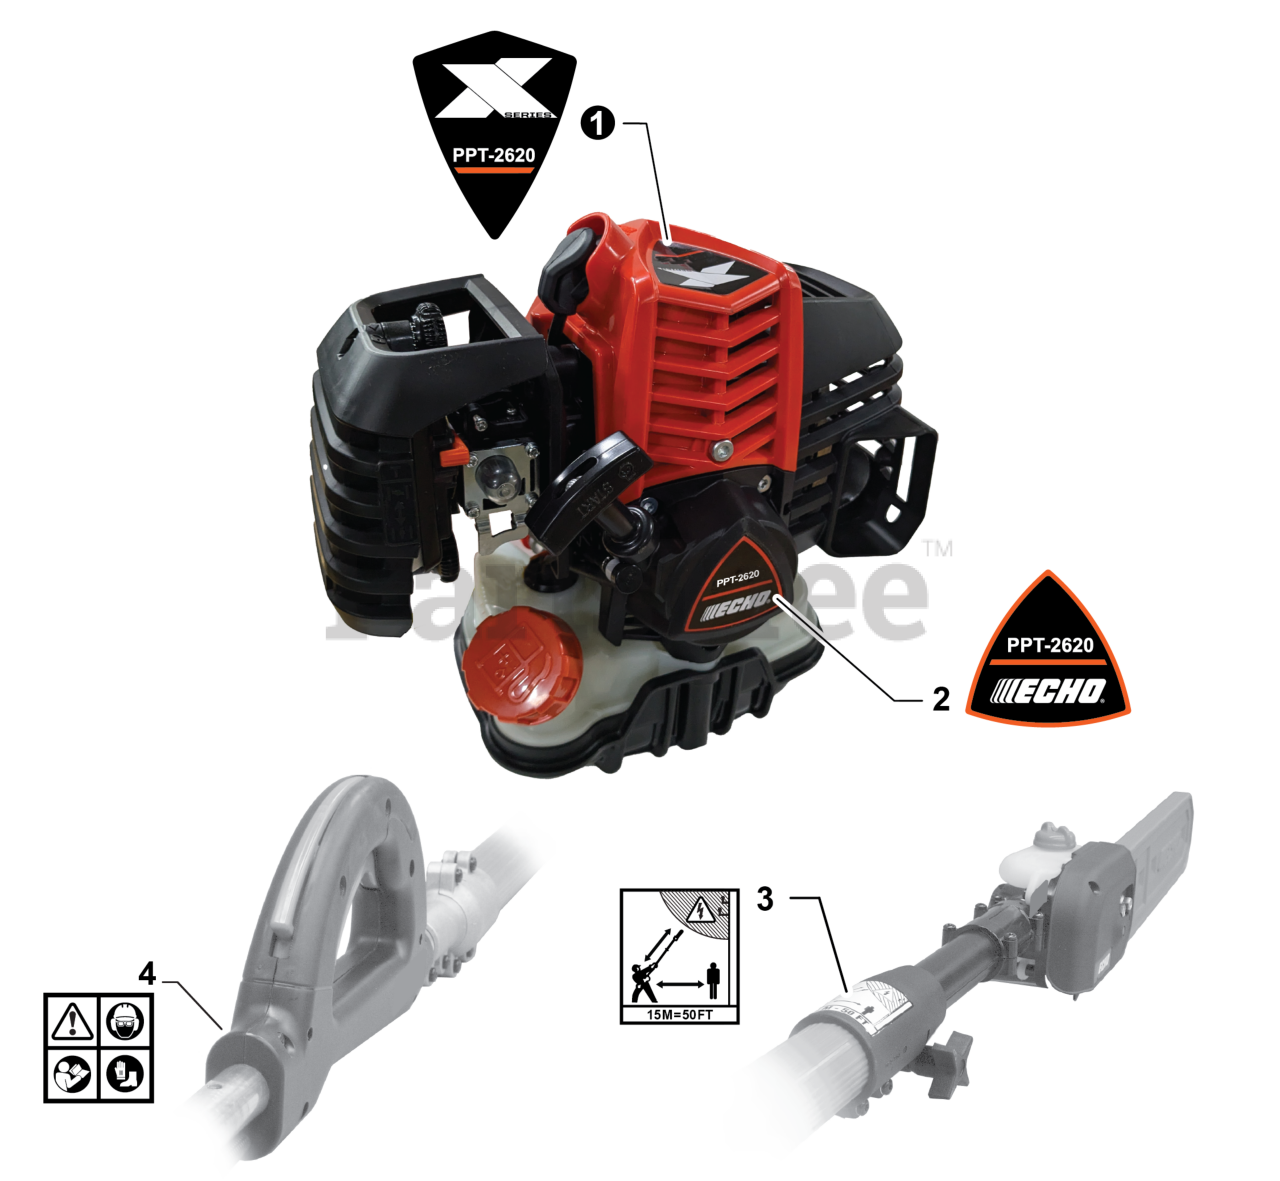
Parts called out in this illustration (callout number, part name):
1	LABEL - MODEL PPT-2620
2	LABEL - RECOIL STARTER - PPT-2620
3	LABEL - CAUTION
4	LABEL - CAUTION - ISO
